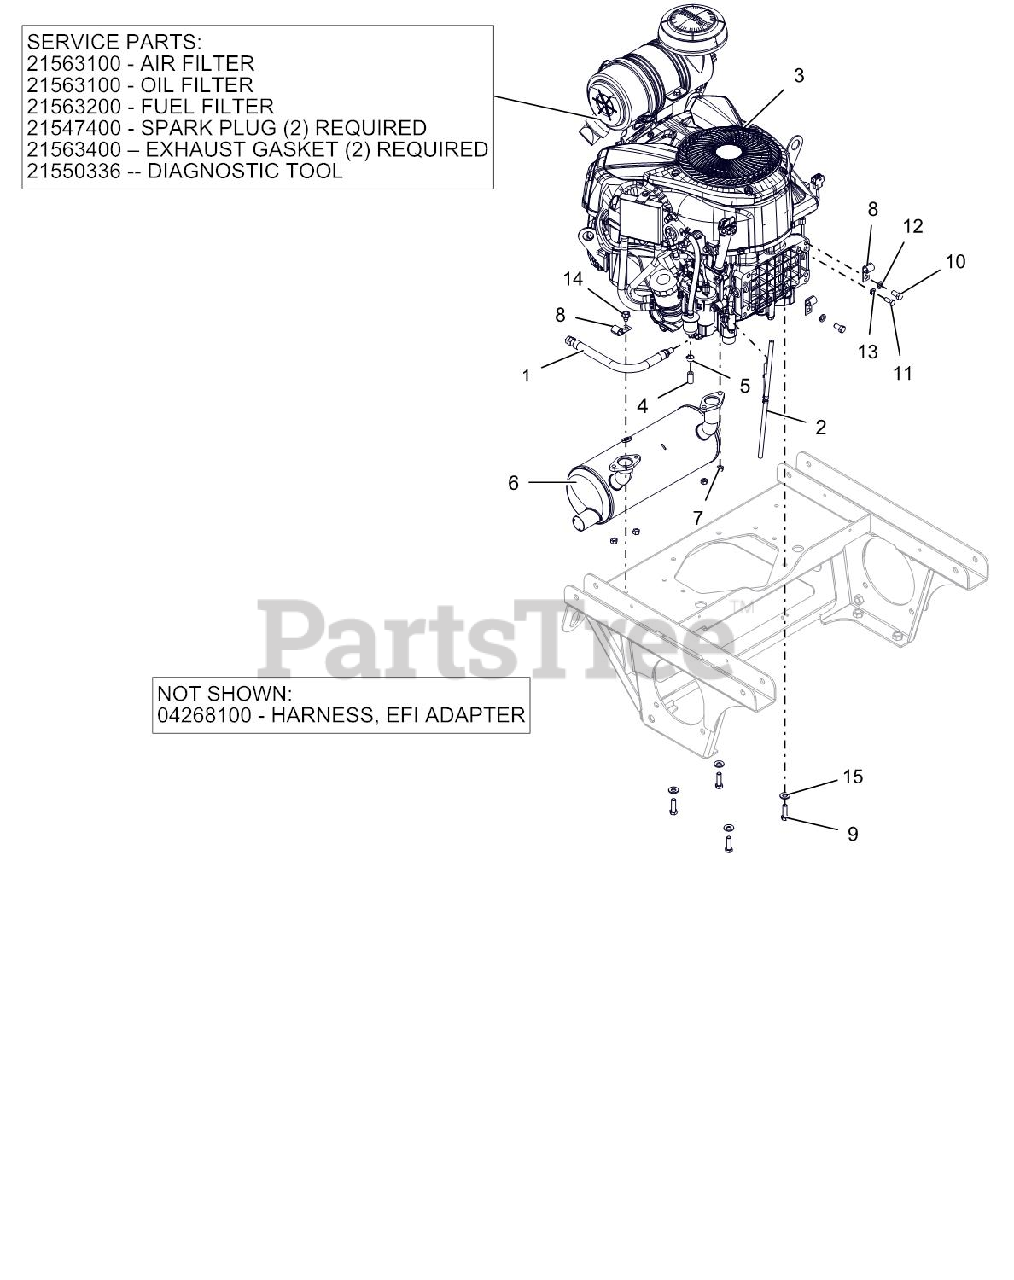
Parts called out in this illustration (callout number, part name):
1	HOSE, OIL DRAIN
2	ASM, YAMAHA VAPOR LINE
3	GASKET, MUFFLER YAMAHA 824
3	FILTER-FUEL YAMAHA 824
3	AIR FILTER (OUTER) - YAMAHA
3	FILTER, OIL - YAMAHA 824
3	PLUG, SPARK
3	DIAGOSTIC TOOL, YAMAHA MXV
3	ENGINE, YAMAHA MX775V-EFI
4	HOSE, .25 LOW-PERM BULK GAS
5	CLAMP, FUEL LINE
6	MUFFLER, YAMAHA
7	NUT-LK-TOP M8-1.25 YWZC
9	BLT-HEX.38-16X1.25 G5YZ NYTORQ
10	@BLT-HEX .38-16X.75 GR5 YWZC
11	@BLT-HEX .31-18X.75 GR5 YWZC
12	@WSHR-LK .38X.094 REG YWZC
13	@WSHR-LK .31X.078 REG YWZC
14	@SCR-TAP .38-16X.50 HWH TR YWZ
15	WASHER, 3/8" SPRING DISC
16	HARNESS, EFI ADAPTER
